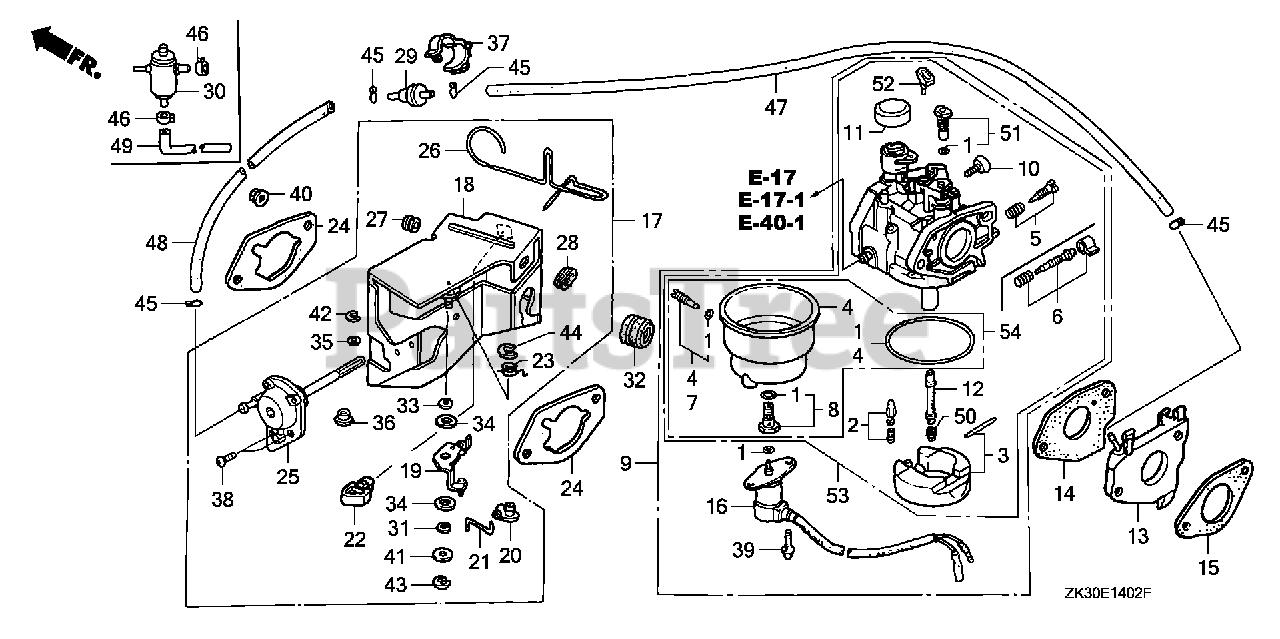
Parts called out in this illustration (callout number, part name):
1	GASKET SET (CARBURETOR NO.)
2	VALVE SET, FLOAT
4	CHAMBER SET, FLOAT (CARBURETOR NO.)
6	SCREW SET, PILOT (CARBURETOR NO.)
7	SCREW SET, DRAIN
8	SCREW SET (CARBURETOR NO.)
9	CARBURETOR ASSY. (BE82B C)
10	SCREW, THROTTLE STOP
11	CAP, CHOKE DUST
12	NOZZLE, MAIN (CARBURETOR NO.)
13	INSULATOR, CARBURETOR
14	GASKET, CARBURETOR
15	GASKET, INSULATOR
16	VALVE ASSY., SOLENOID
17	STAY ASSY., MANUAL CHOKE
18	STAY, SOLENOID
19	LEVER, CHOKE
20	JOINT, ROD
21	ROD, CHOKE
22	STOPPER, CHOKE ROD
23	SPRING, MANUAL CHOKE
24	GASKET, AIR CLEANER
25	DIAPHRAGM ASSY.
26	ROD, CHOKE CONTROL
27	GROMMET, CHOKE ROD
28	GUIDE, CHOKE ROD
29	VALVE, DASHPOT CHECK
31	BUSH, ARM PIVOT
32	GROMMET, FENDER
33	WASHER, CHOKE LEVER
34	SEAL, CHOKE LEVER
35	WASHER, THRUST (2.7X8)
36	COLLAR, LEVER
37	CLIP, WIRE HARNESS
38	SCREW, PAN (5X12)
39	SCREW-WASHER (5X12) (CARBURETOR NO.)
40	NUT, FLANGE (6MM)
41	WASHER, PLAIN (5MM)
42	E-RING (2MM)
43	E-RING (4MM)
44	E-RING (7MM)
45	CLIP, TUBE (B7)
47	BULK HOSE, VACUUM (3.5X8000) (3.5X75)
48	BULK HOSE, VACUUM (3.5X8000) (3.5X130)
50	JET, MAIN (#95) (CARBURETOR NO.)
50	JET, MAIN (#98) (CARBURETOR NO.)
50	JET, MAIN (#100) (CARBURETOR NO.)
51	JET SET, PILOT (#35) (CARBURETOR NO.)
52	COLLAR, SETTING (CARBURETOR NO.)
53	CARBURETOR ASSY. (BE82E A)
54	BOLT KIT, FUEL CHAMBER (CARBURETOR NO.)
